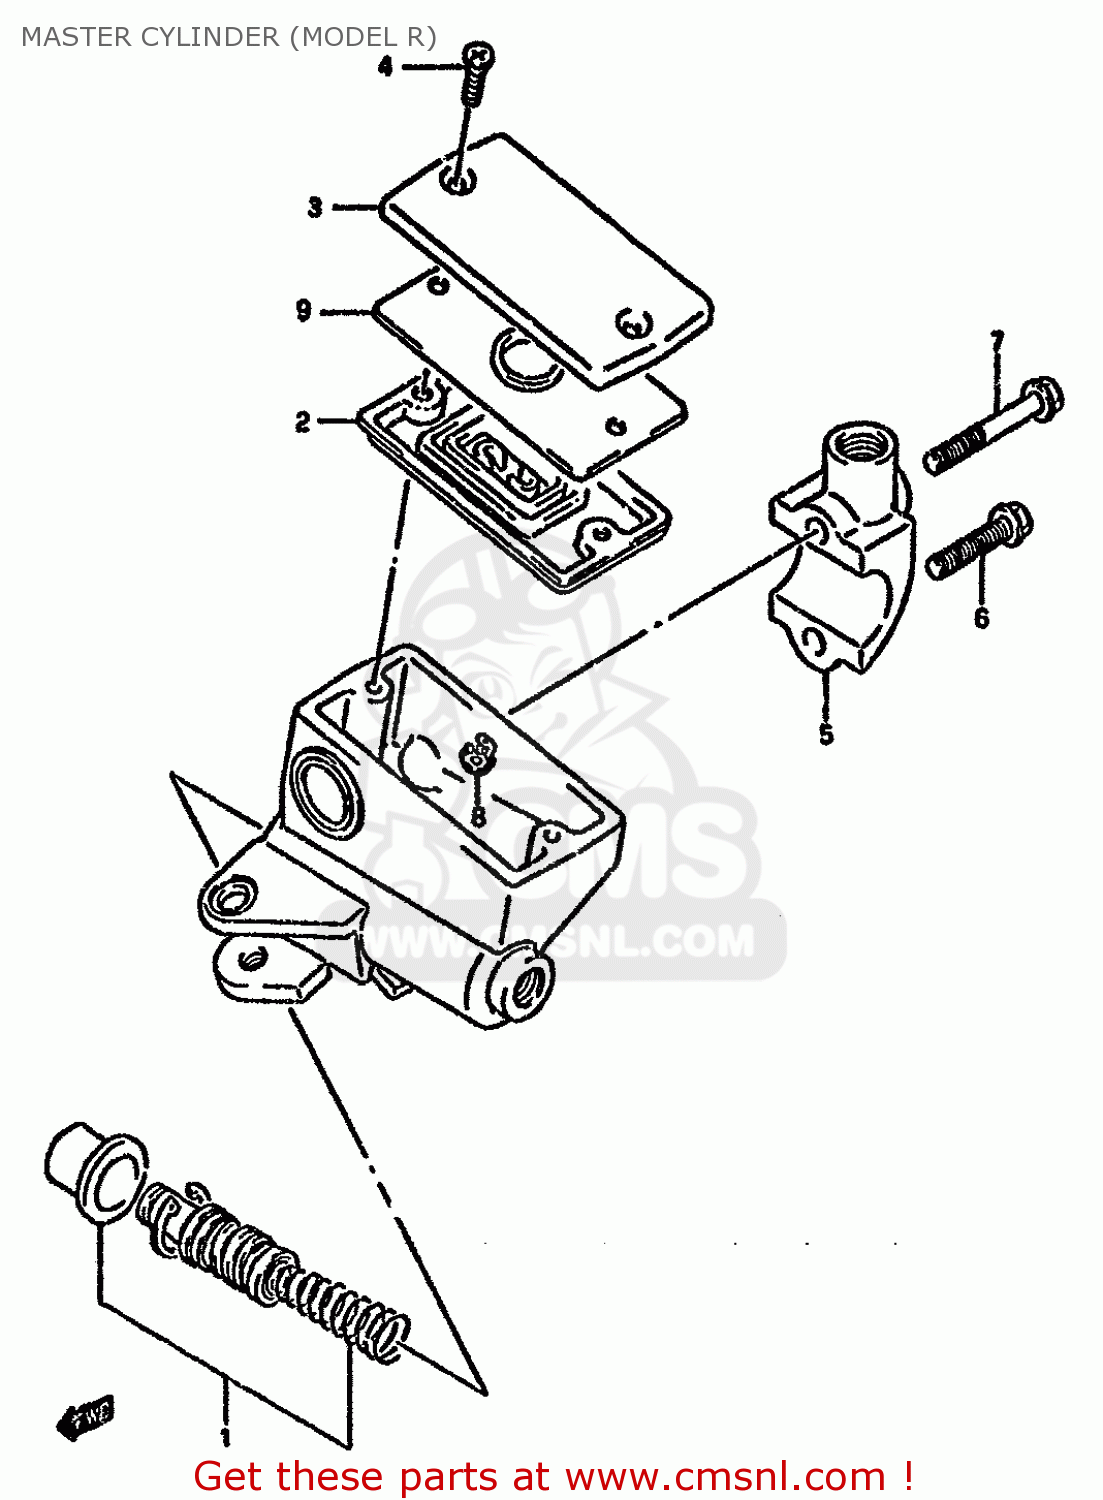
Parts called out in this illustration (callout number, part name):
1	PISTON & CUP SET
2	3
3	CAP
4	SCREW
5	HOLDER
6	BOLT(6X25)
7	BOLT(6X38)
8	PROTECTOR
9	PLATE,DIAPHRAGM
